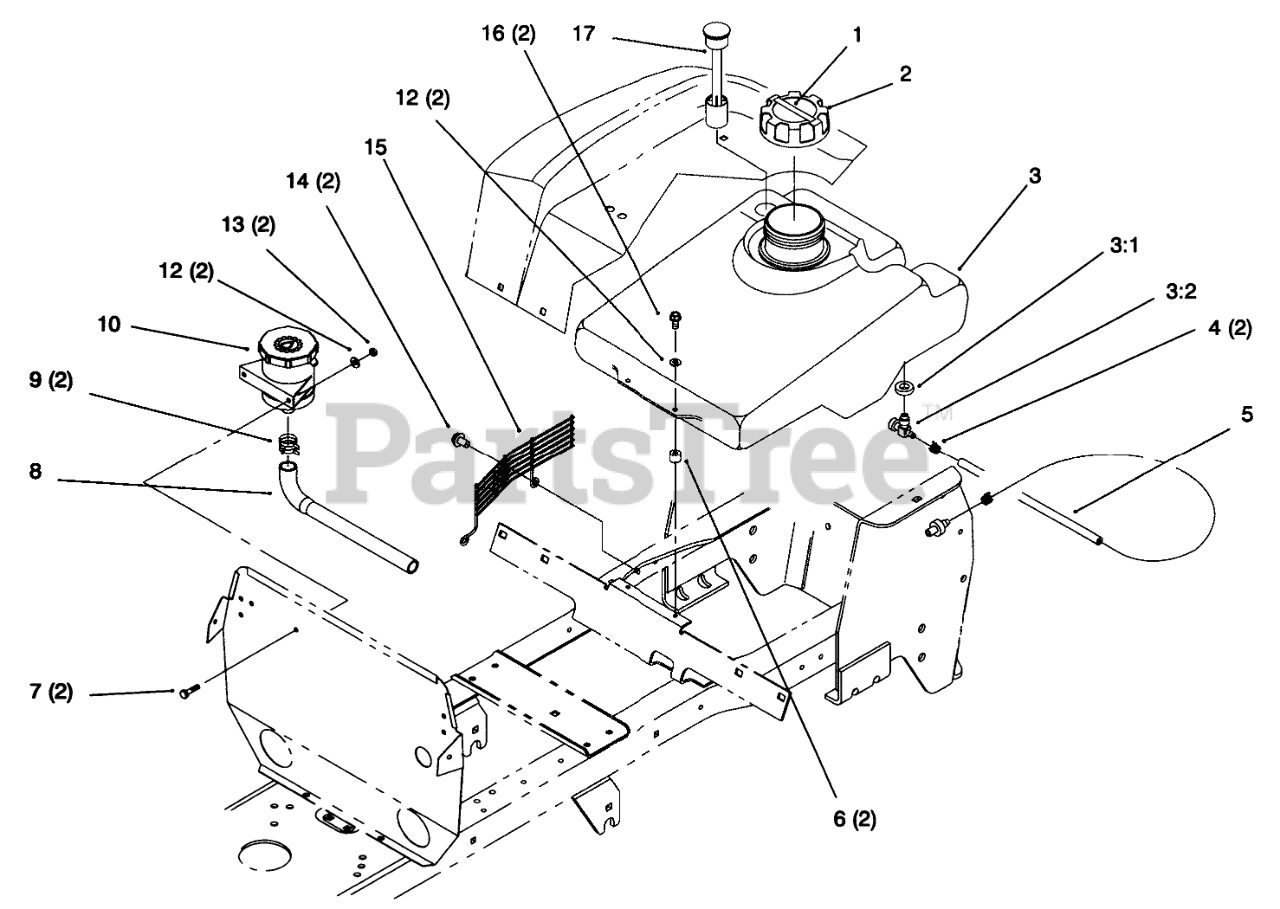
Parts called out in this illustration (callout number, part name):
1	Decal-Oil Check
2	GAS CAP ASM
3	Tank-Gas
3:1	VALVE-FUEL
3:2	BUSHING
4	CLAMP-HOSE
5	HOSE - FUEL LINE
6	SPACER - FUEL TANK
7	SCREW-HH
8	HOSE - HYDRO
9	CLAMP-HOSE
10	ASS'Y-RESERVOIR
12	WASHER-FLAT
13	NUT-LOCK, NI
14	Screw-HH (Only On: 72064)
15	Guard-Fan (Only On: 72064)
16	SCREW-HH
